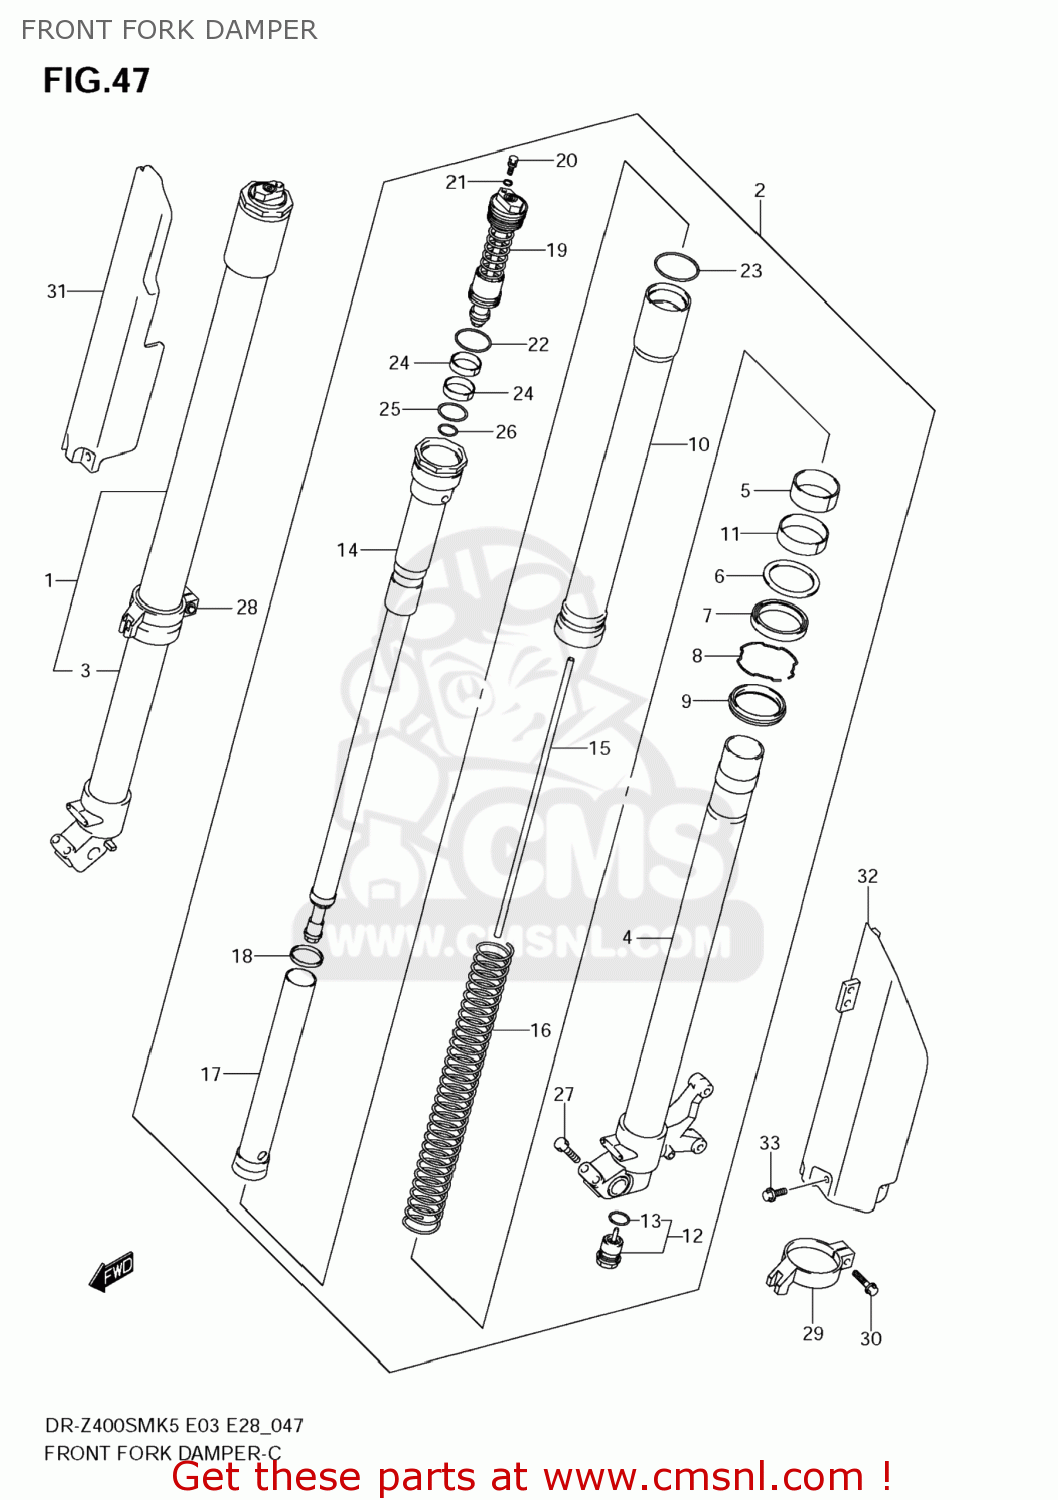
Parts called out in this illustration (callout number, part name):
1	DAMPER ASSY,FR FORK,R
2	DAMPER ASSY,FR FORK,L
3	TUBE,INNER,R
4	TUBE,INNER,L
5	BUSH,GUIDE
6	SPACER,SEAL
7	SEAL,OIL
8	RING,OIL SEAL STOPPER
9	SEAL,DUST
10	TUBE,OUTER
11	BUSH,SLIDE
12	BOLT,CTR
13	O RING
14	DAMPER
15	ROD,PUSH
16	SPRING,FR
17	COLLAR,SPRING
18	SPRING SEAT
19	BOLT,FORK
20	BOLT,PLUG
21	O RING,PLUG
22	O RING
23	O RING
24	BUSH,FORK BOLT SLIDE
25	O RING
26	O RING
27	BOLT
28	GUIDE,PROTECTOR,R
29	GUIDE,PROTECTOR,L
30	BOLT
31	PROTECTOR,FR FORK,R
32	PROTECTOR,FR FORK,L
33	BOLT(6X10)
